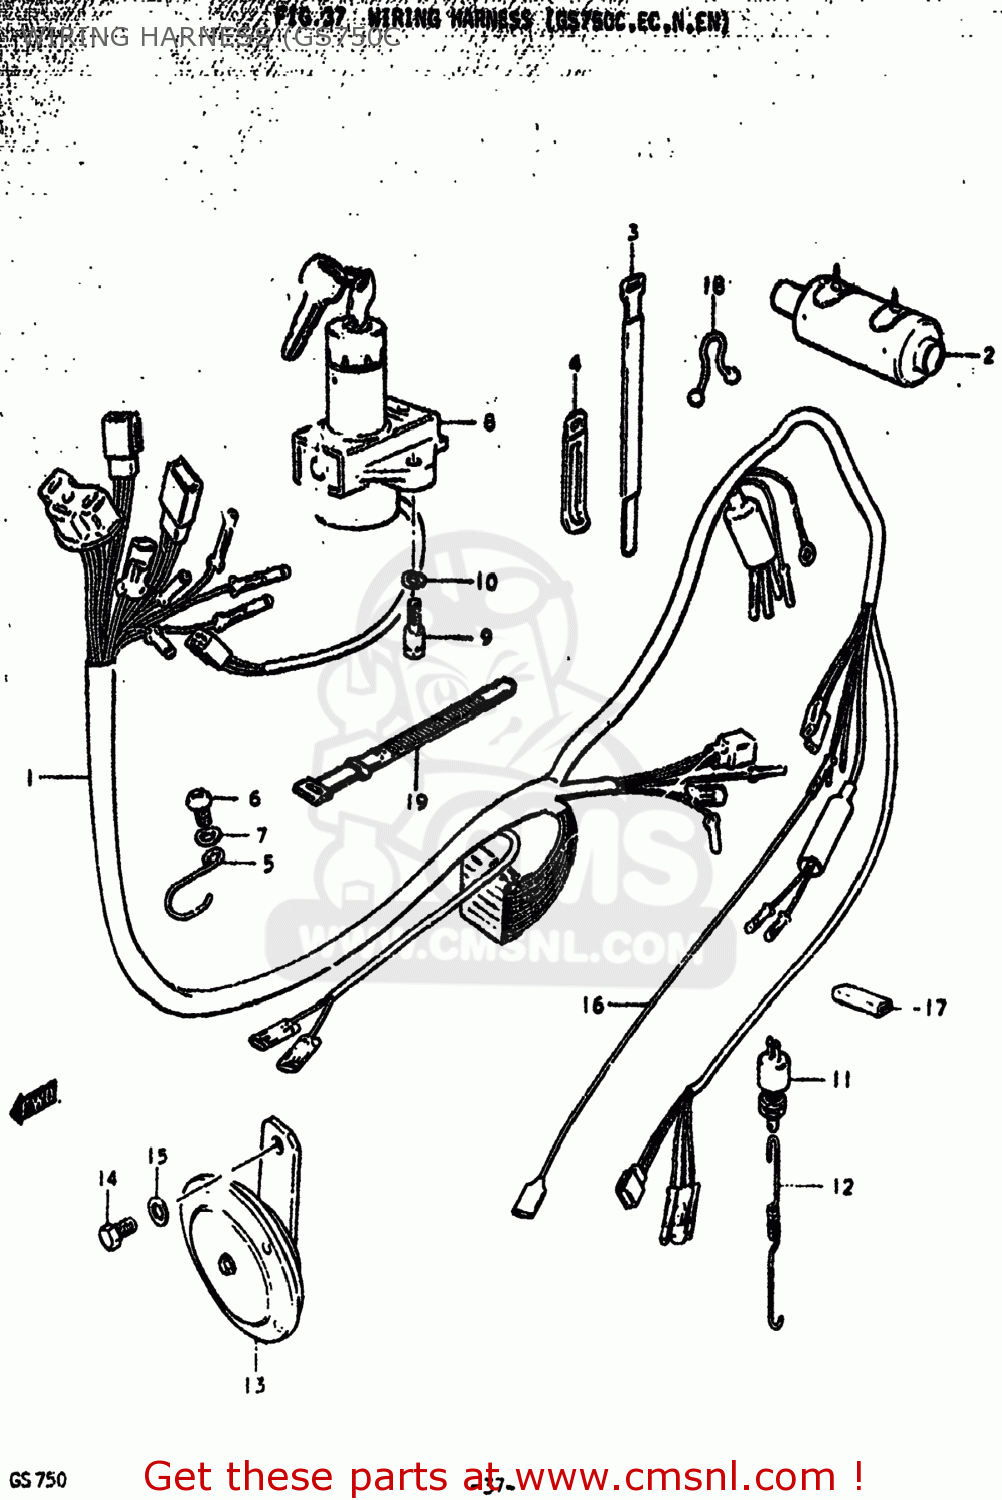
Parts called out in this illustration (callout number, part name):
1	HARNESS,WIRING
2	BOOT,WIRING HARNESS
3	CLAMP
4	CLAMP
5	GUIDE,WIRING HARNESS
6	SCREW 6X12
7	WASHER
8	LOCK ASSEMBLY,STEERING
9	BOLT
10	LOCK WASHER
11	SWITCH ASSY,BRAKE LAMP
12	SPRING
13	HORN ASSY
14	BOLT 8X12
15	WASHER
16	WIRE
17	PROTECTOR,WIRING HARNESS
18	CLAMP
19	CLAMP(L:120)
